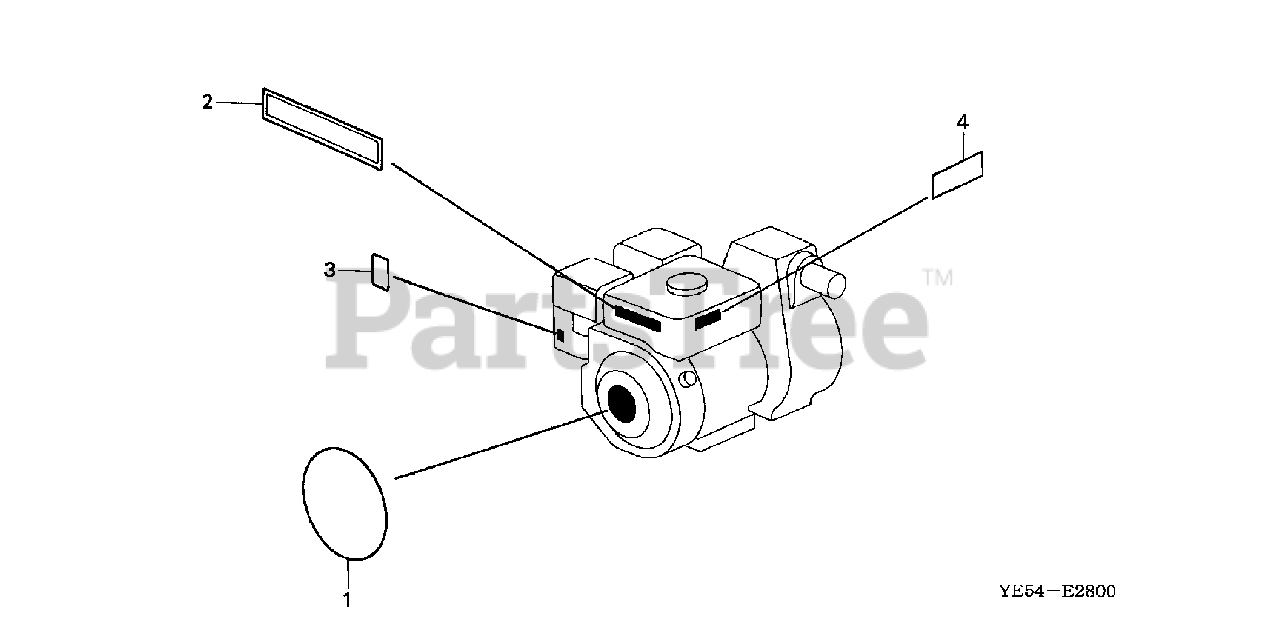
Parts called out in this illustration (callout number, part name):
1	EMBLEM (INTERNAL)
1	EMBLEM
2	LABEL, CAUTION
3	MARK, CHOKE
4	MARK, OIL ALERT (E)
